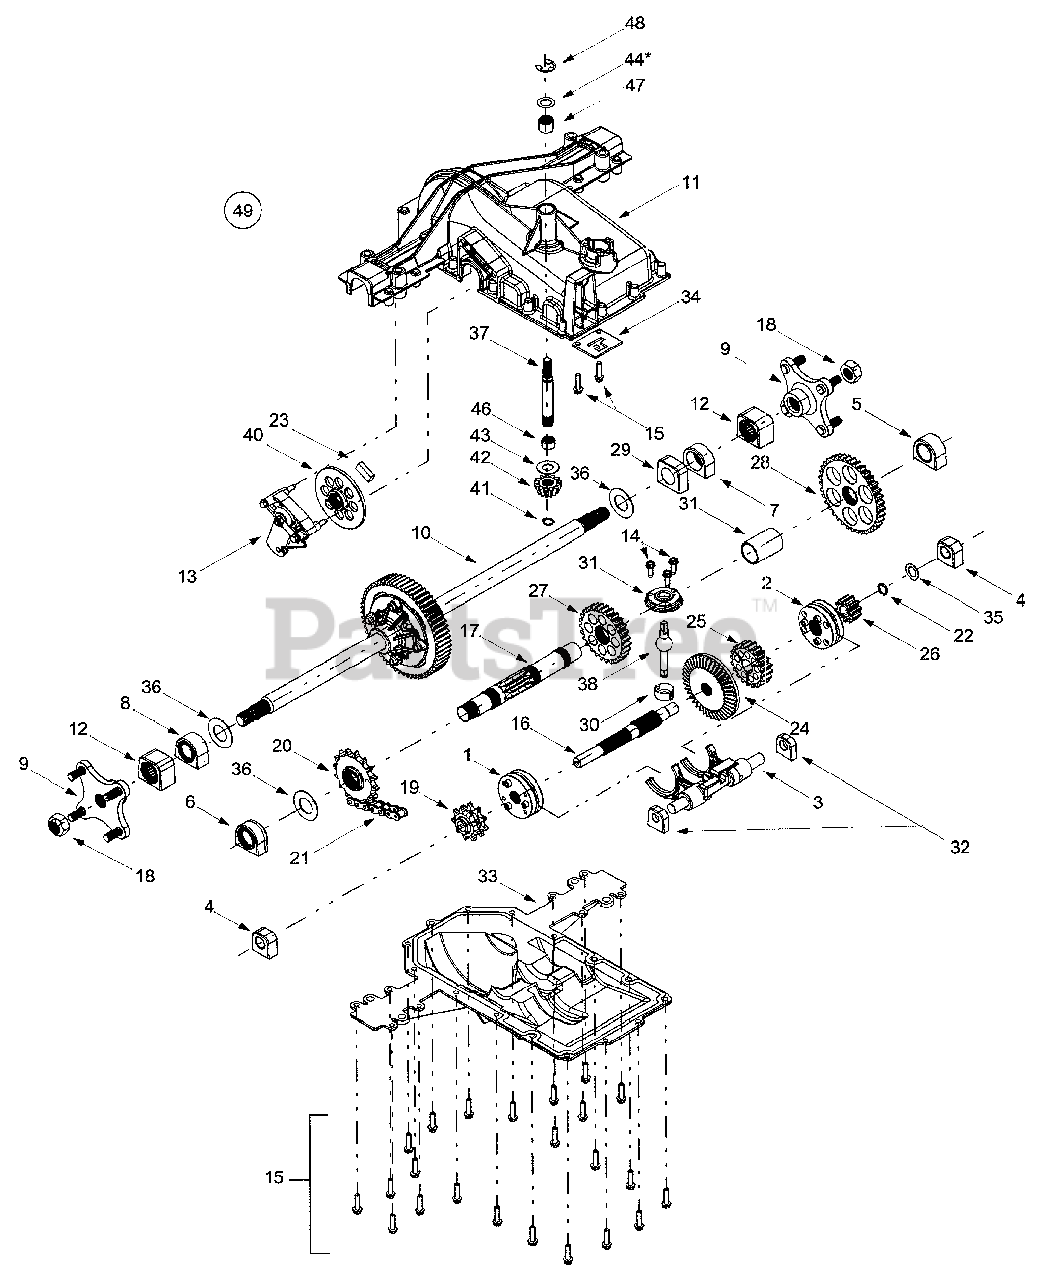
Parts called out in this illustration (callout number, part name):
1	Reverse Collar Assembly
2	Hi-Lo Collar Assembly
3	Shift Fork Assembly
4	Detent Block Assembly
5	Output Bearing Block Assembly
6	Output Seal Bearing Block Assembly
7	Inboard Sealed Axle Block Assembly
8	Inboard Sealed Axle Block Assembly
9	Wheel Hub Assembly
10	Differential Axle Assembly
11	Upper Housing
12	Axle Bearing Block Assembly
13	Brake Assembly
14	Self-tapping Screw, 1/4-20 x .75
15	Self-tapping Screw, 1/4-20 x 1.0
16	Drive Shaft
17	Output Shaft
18	Nut, 3/4-16
19	9-tooth Sprocket
20	16-tooth Sprocket
21	22-link Chain, .625
22	External Snap Ring
23	Brake Pad
24	41-tooth Bevel Gear
25	20-tooth Spur Gear
26	10-tooth Spur Gear
27	27-tooth Spur Gear
28	37-tooth Spur Gear
29	Inner Axle Bearing Block
30	Shifter Insert
31	Shifter Cover
32	Shifter Bearing Block
33	Lower Housing
34	Lockout Plate
35	Flat Washer, 5/8 x 1.0
36	Flat Washer, 1.01 x 1.86 x .060
37	Input Shaft
38	Shift Lever
40	Disc Brake
41	Retaining Ring, .56
42	13-tooth Bevel Gear
43	Flat Washer
44	Flat Washer, 5/8 x 1.0 x .030
46	Needle Bearing
47	Needle Bearing
48	E-ring, .75
49	Transmission Assembly Complete
